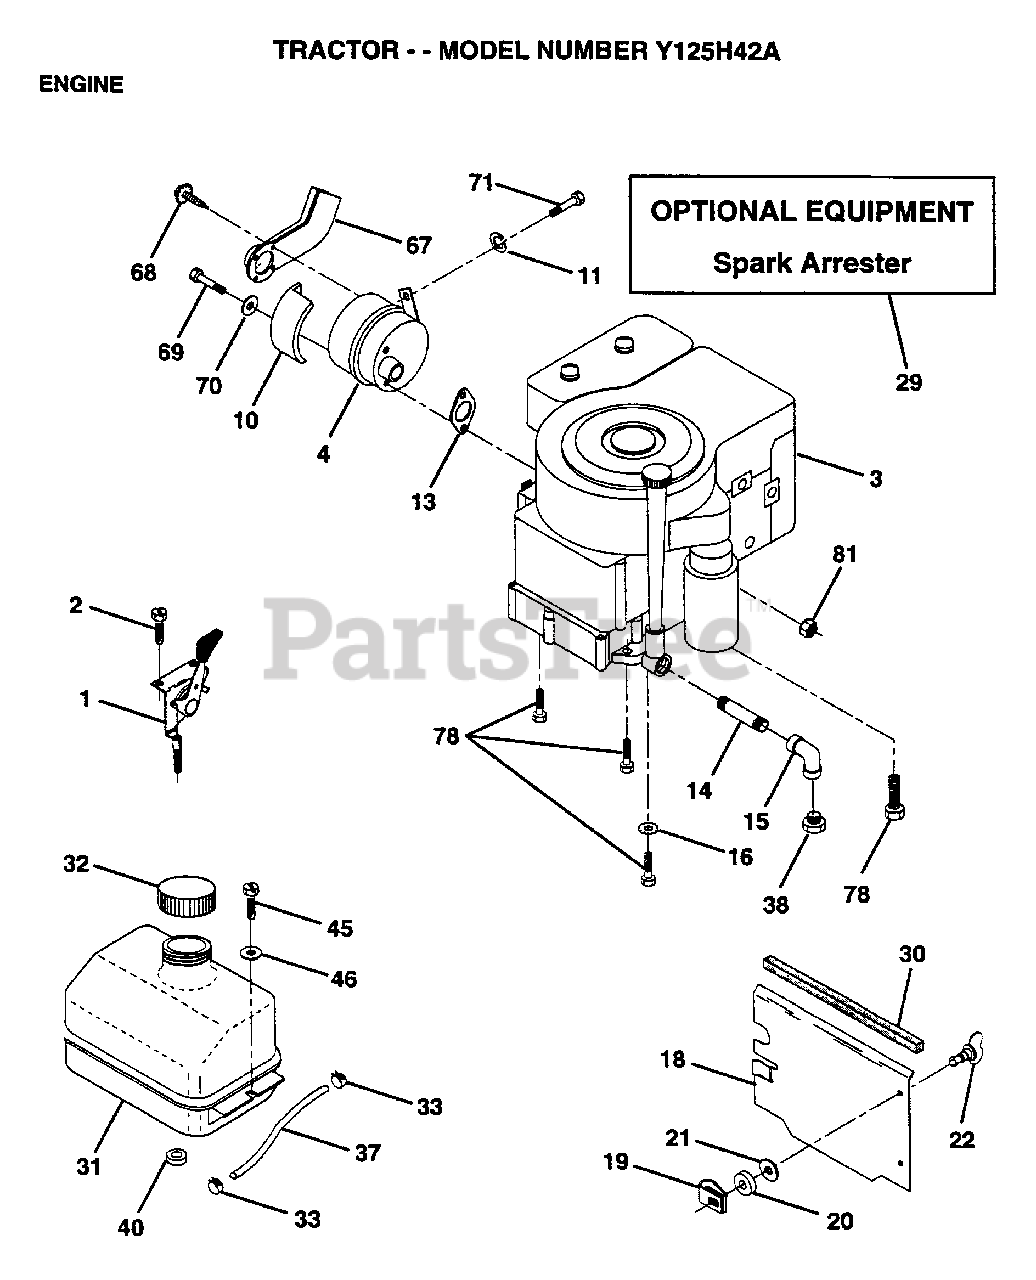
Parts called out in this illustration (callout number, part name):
1	THROTTLE CONTROL
2	SCREW LT
4	MUFFLER LTV
10	SHIELD HEAT LTV
11	LOCKWASHER
14	PIPE NIPPLE
15	ELBOW
16	LOCKWASHER
18	SHIELD HEAT
19	RECEPTACLE LT
20	RETAINER LT
21	WASHER
22	STUD.1/4.TURN
31	TANK.FUEL.LT.
32	CAP ASM FUEL
33	HOSE CLAMP
37	LINE FUEL
45	SCREW HEX CRT
46	WASHER
67	DEFLECTOR MUFFLER
69	"BOLT,HEX"
70	WASHER T
71	BOLT HXHD FIN
78	SCREW
81	NUT
